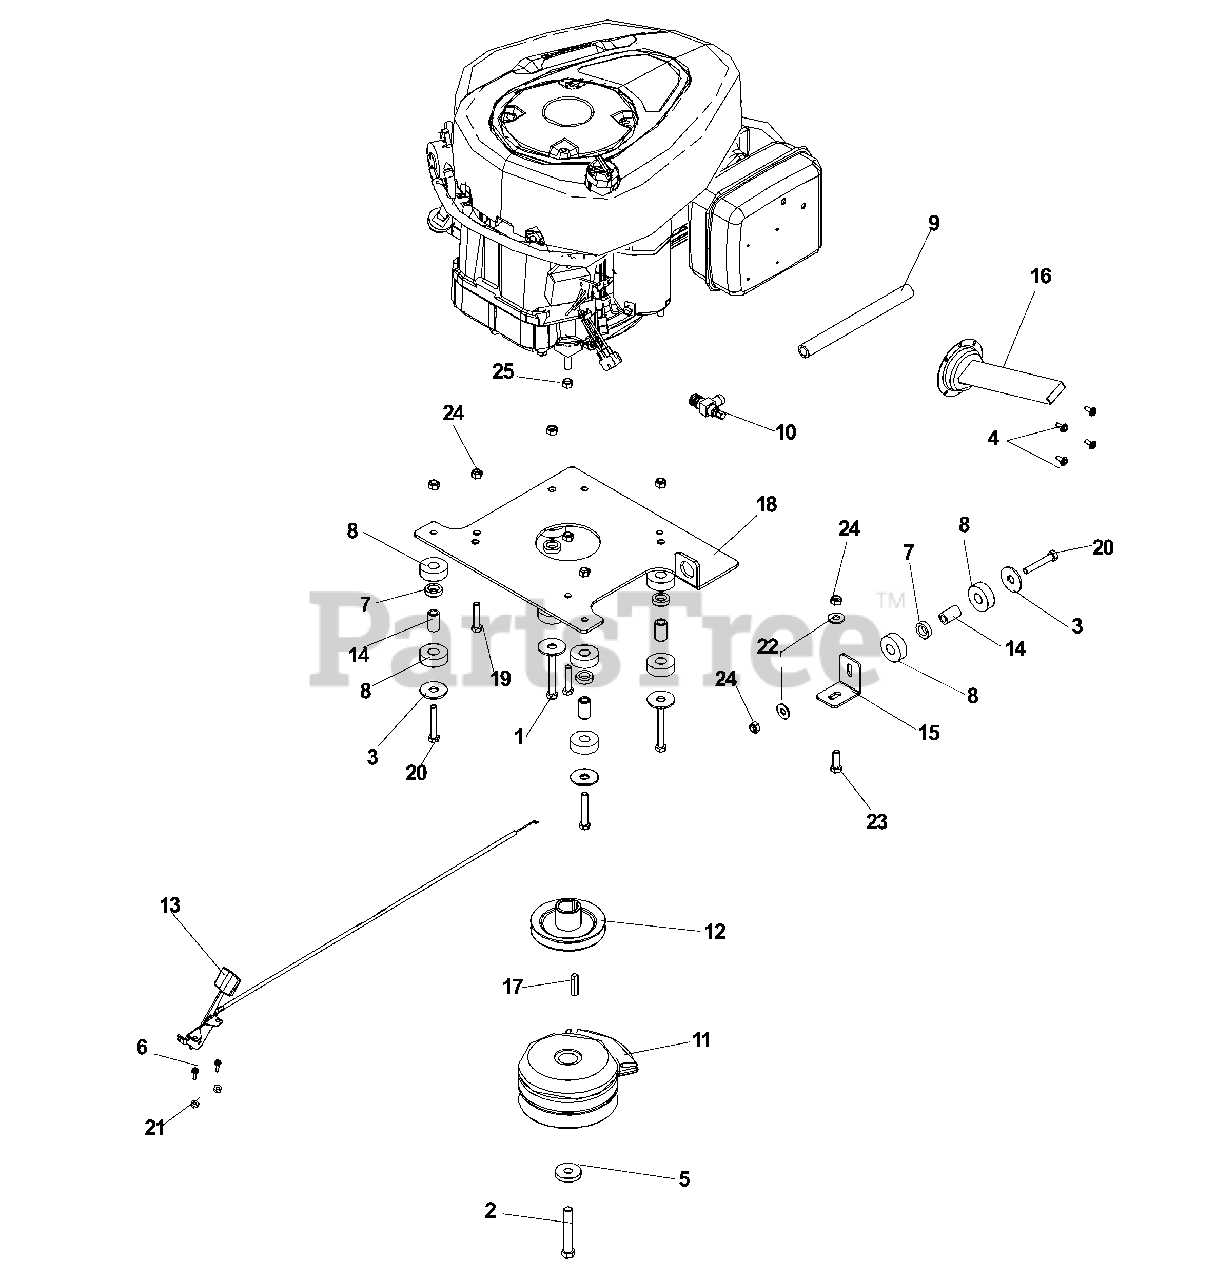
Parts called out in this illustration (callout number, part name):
1	HCS 5/16C X 2-3/4
2	HCS 7/16-20 X 2-3/4
3	WASHER 7/16 FLAT ZD
4	SCREW, TAP #10-16 X 1/2
5	WASHER .43X1.38X.25
6	SCREW #10-24 X 5/8
7	ISO-MOUNT INSERT
8	ISO-MOUNT BUSHING
9	OIL DRAIN HOSE
10	OIL DRAIN
11	ELEC. CLUTCH
12	ENGINE PULLEY
13	THROTTLE CABLE
14	ISO MT. BUSHING
15	ISO MT. BRKT.
16	MUFFLER EXT.(PAINTED)
17	KEY 1/4`SQ X 1-1/4`
18	ISO-MT SPDZTR
19	CAPSCREW 5/16 X 1/1/2 HEX HEAD
20	HCS 5/16-18X2
21	NUT 10-24 NYLOC
22	FLAT WASHER 5/16 SAE
23	HCS 5/16C X 1
24	NUT 5/16 NYLOC
